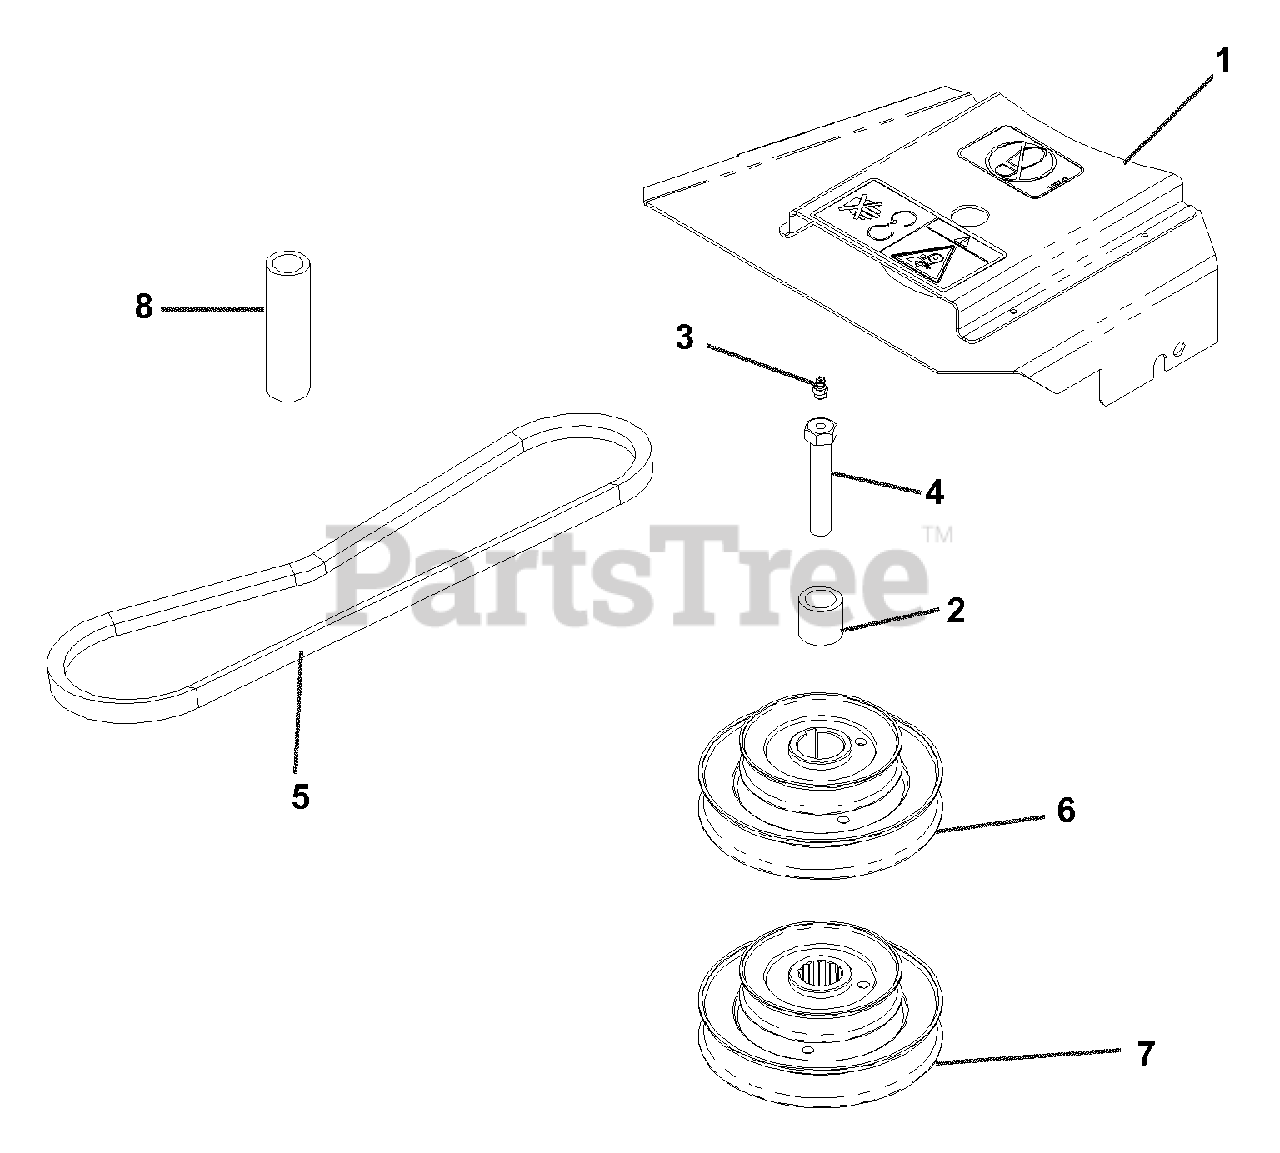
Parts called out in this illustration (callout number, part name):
1	48 SHIELD
2	SPACER
3	ZERK
4	HCS 7/16 X 2.5, SPEC.
6	STACKED SHEAVE 42-48
6	STACKED SHEAVE 52
6	STACKED SHEAVE 61
7	DOUBLE HEX STACKED SHEAVE 42-48
7	DOUBLE HEX STACKED SHEAVE 52
7	DOUBLE HEX STACKED SHEAVE 61
8	STOP -
